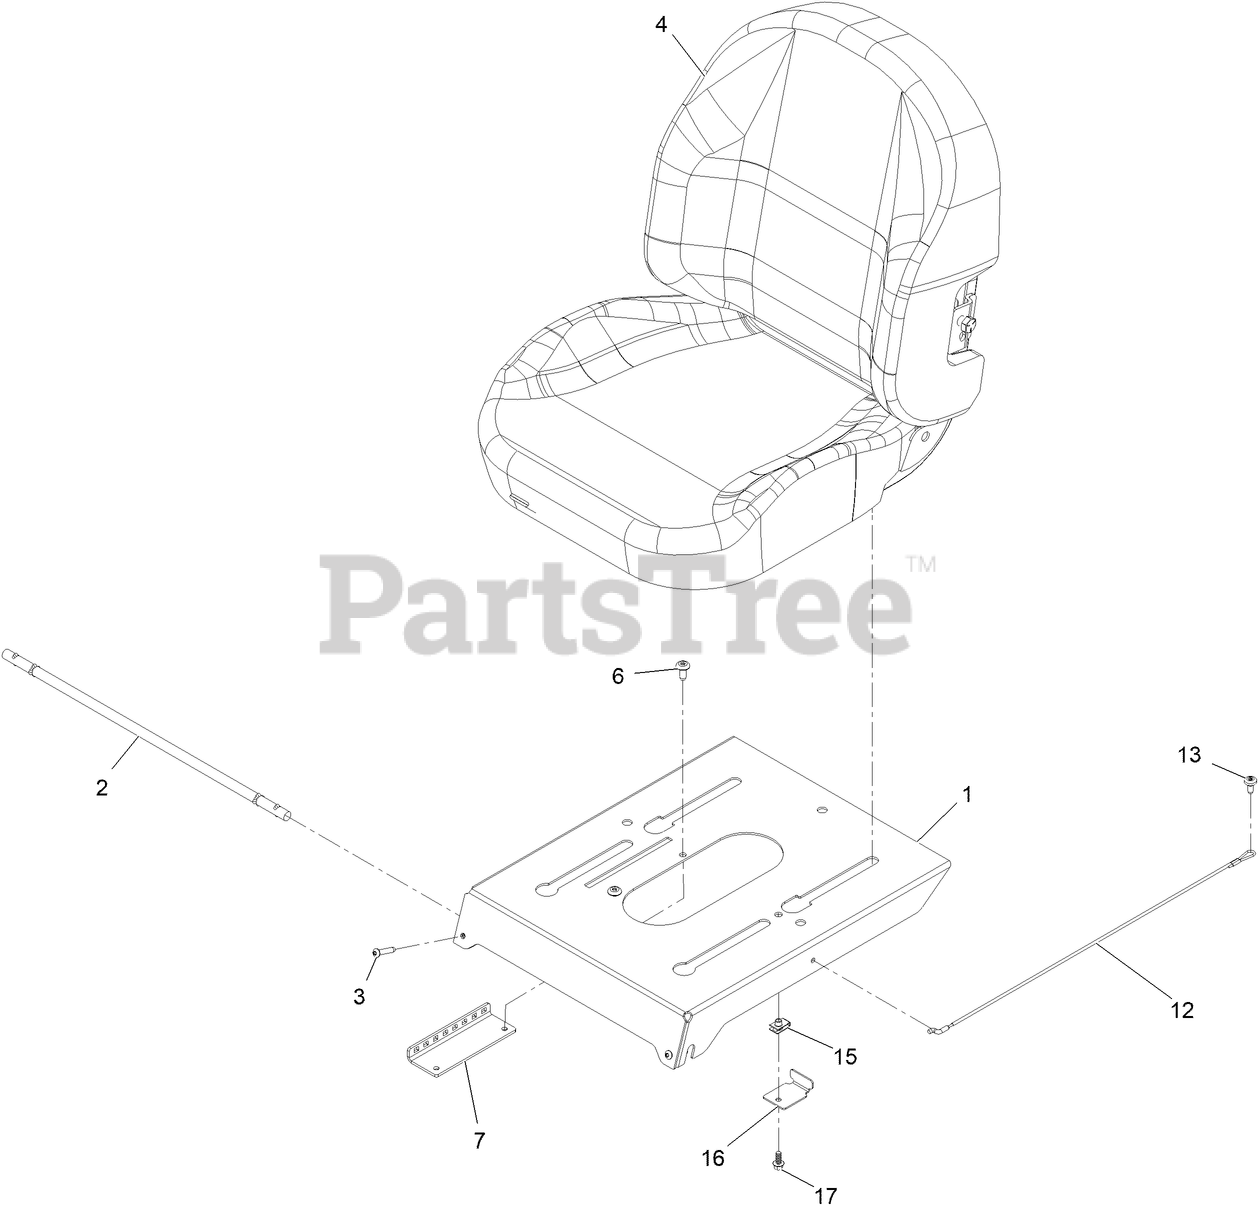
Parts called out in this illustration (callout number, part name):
2	ROD-PIVOT
3	SCREW-TTH, THREAD ROLLING
4	ASM-Seat Exmark
7	BRACKET-LATCH, SEAT
12	CABLE-LANYARD
13	SCREW-SHOULDER
16	Bracket-Stop, Seat
17	SCREW-HHF
